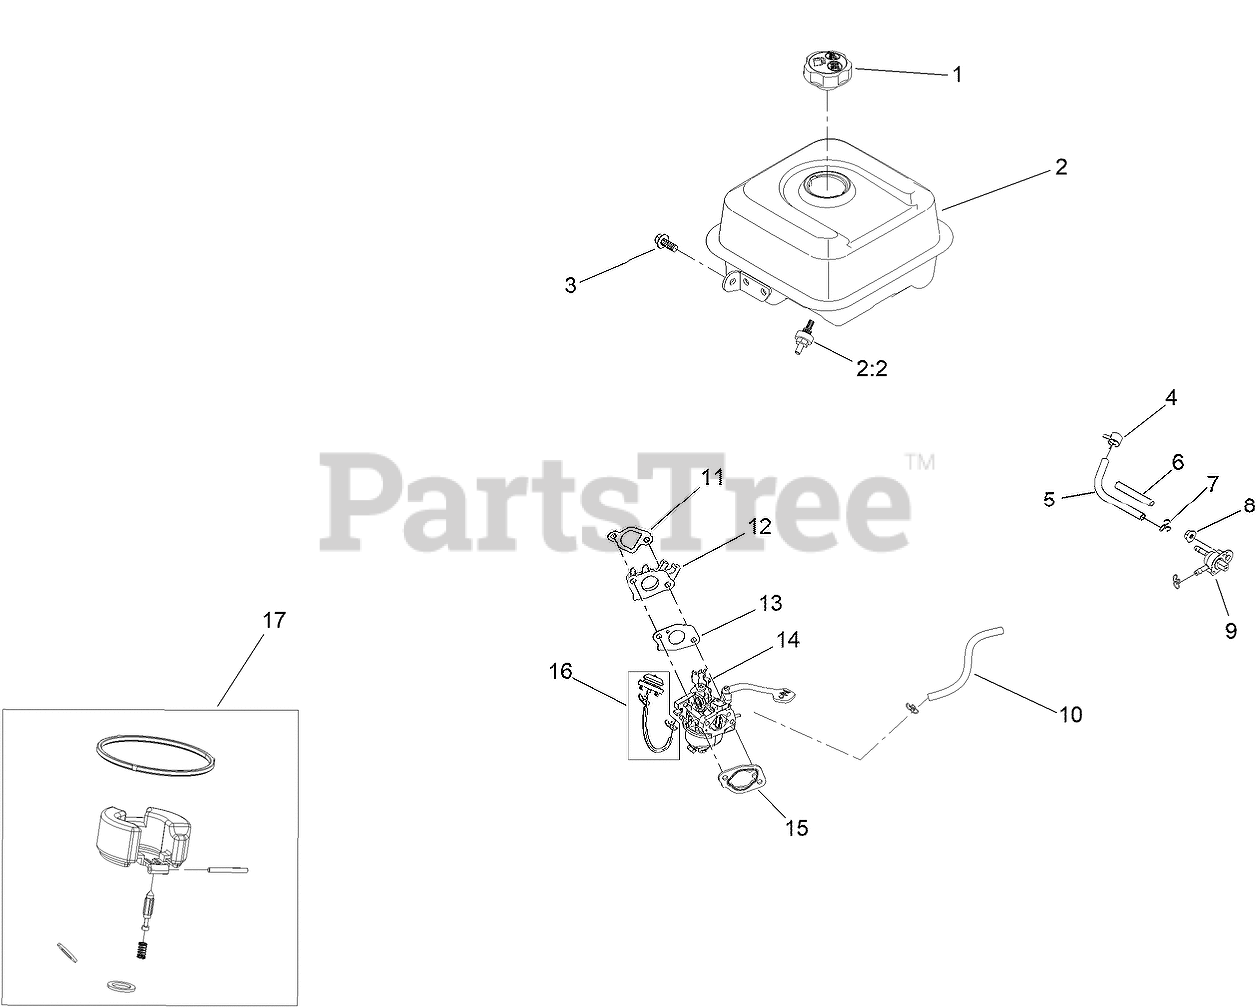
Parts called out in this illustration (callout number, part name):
1	CAP-FUEL
2	FUEL TANK AND FILTER ASM
2:2	FILTER-FUEL
3	SCREW-HHF
4	CLAMP-HOSE
5	HOSE-FUEL
6	SLEEVE-ABRASION
7	CLAMP-HOSE
8	NUT-FLANGE
9	VALVE-FUEL
10	HOSE-FUEL
11	GASKET-CARBURETOR
12	INSULATOR-CARBURETOR
13	GASKET-CARBURETOR
14	CARBURETOR ASM
15	GASKET-CARBURETOR
16	PRIMER KIT
17	INTERNAL CARB SERVICE KIT
